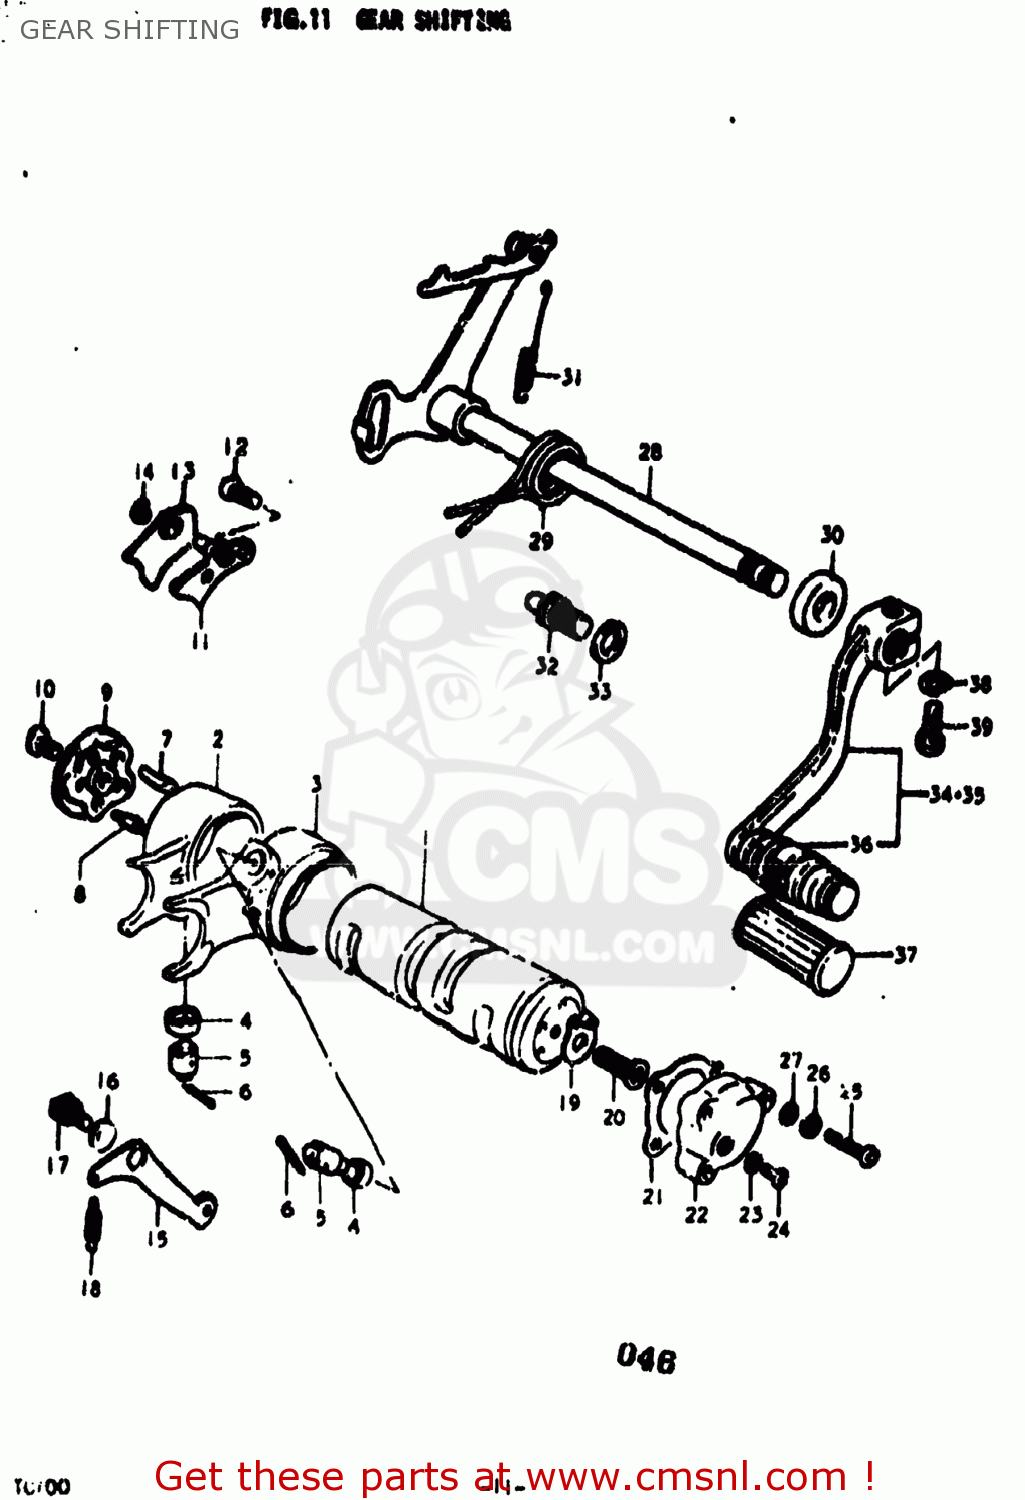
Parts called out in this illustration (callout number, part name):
1	CAM,GEAR SHIFT
2	FORK,GEAR SHIFT NO.1
3	FORK,GEAR SHIFT NO.2
4	SPACER
5	PIN
6	PIN 25X20
7	PIN(4X20)
8	PIN
9	PLATE,GEAR SHIFT CAM STOPPER
10	SCREW
11	GUIDE,GEAR SHIFT CAM
12	SCREW
13	PAWL,GEAR SHIFTING CAM
14	E RING
15	STOPPER,GEAR SHIFTING
16	WASHER(6.5X16X2.3)
17	BOLT(6X16.1)
18	SPRING
19	CONTACT,GEAR SHIFT SWITCH
20	SCREW
21	GASKET,GEAR SHIFT SWITCH (NAS)
22	SWITCH,NEUTRAL INDICATOR
23	WASHER
24	SCREW
25	SCREW
26	LOCK WASHER
27	WASHER
28	SHAFT,GEAR SHIFT
29	SPRING
30	OIL SEAL
31	SPRING
32	STOPPER,GEAR SHIFT ARM
33	LOCK WASHER
34	LEVER ASSEMBLY,GEAR SHIFTING
35	LEVER ASSEMBLY,GEAR SHIFTING
36	RUBBER,GEAR SHIFT PEDAL
37	RUBBER,GEAR SHIFT PEDAL
38	LOCK WASHER
39	BOLT
